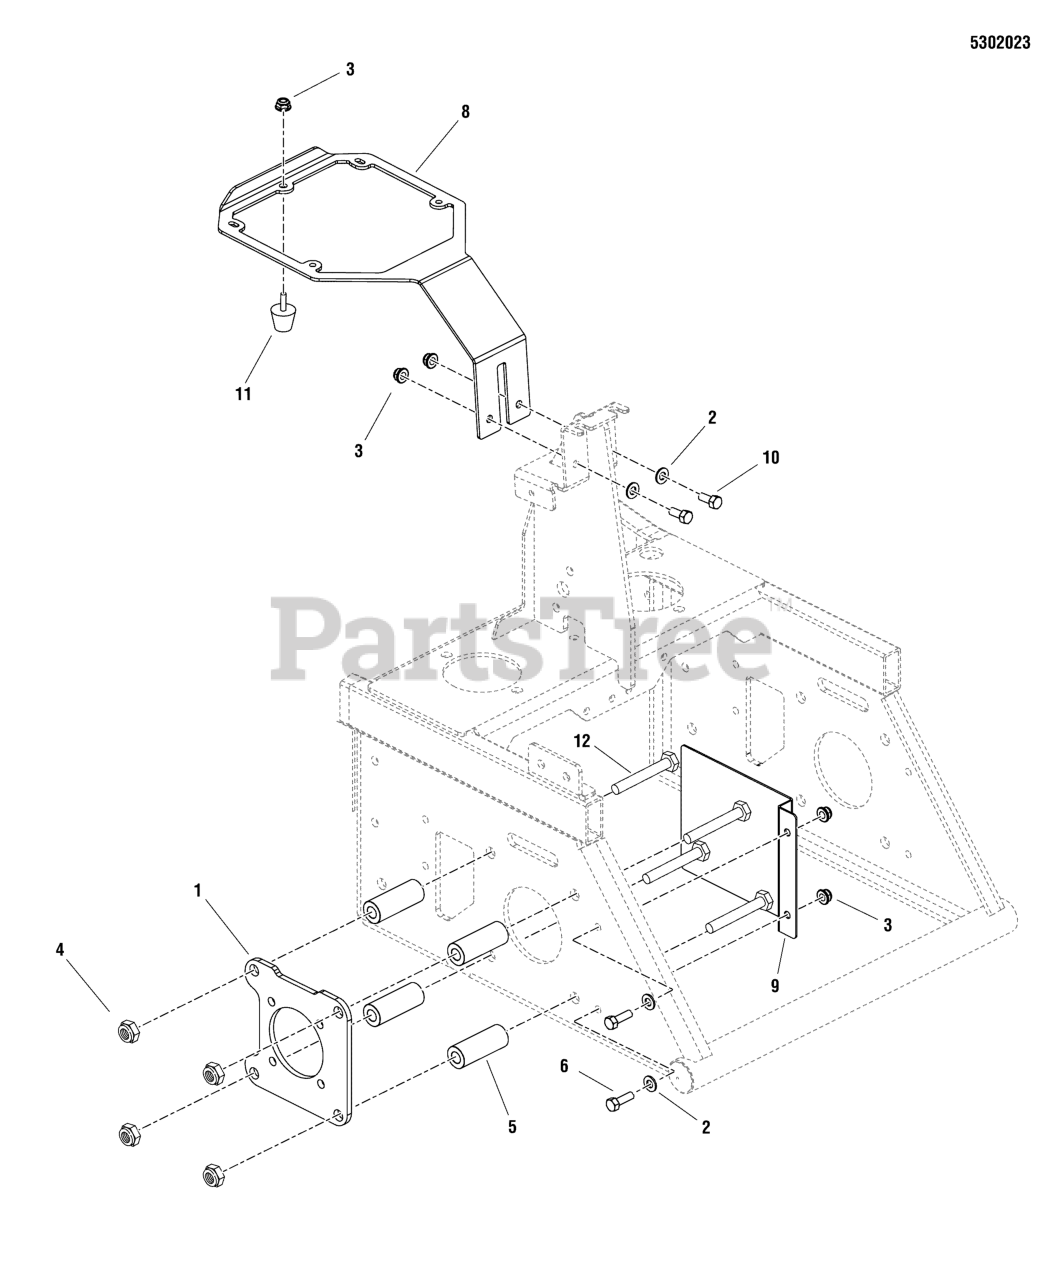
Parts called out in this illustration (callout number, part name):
1	PLATE, SPACER
2	WASHER, 5/16" SAE
3	NUT, 5/16-18 HEX NYLOCK FLANGE
4	NUT, Hex Flange, Nylock, 1/2-13
5	SPACER, .52 X 1.00 X 2.625, YZ
6	BOLT, 5/16-18 X 1 GD5 YZ
7	BOLT, 1/2-13 X 4" GD5 CZ
8	PLATE, COOLER MOUNT BRACKET - RED
9	PLATE, HEAT SHIELD, WHEEL MOTOR, 36-RED
10	BOLT, 5/16-18 X 3/4 GD5
11	BUMPER, RUBBER 5/16-18
